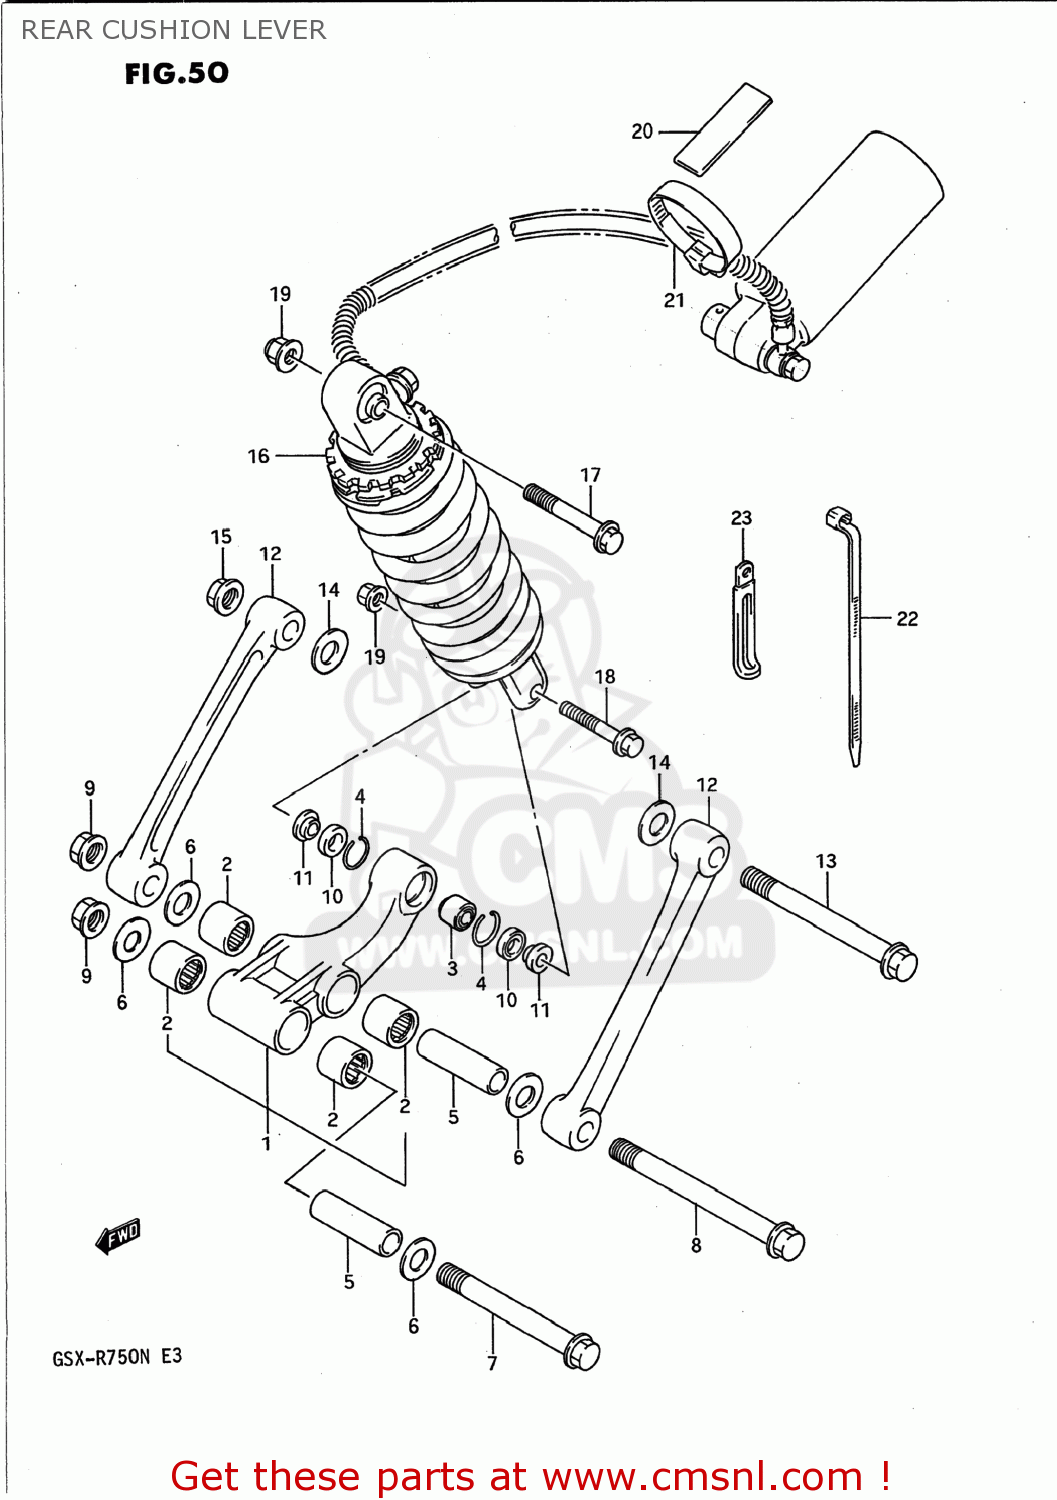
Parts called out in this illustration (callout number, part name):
1	LEVER SET,REAR CUSHION
2	BEARING(20X27X23.5)
3	BEARING,RR CUSHION LEVER
4	RING,STOPPER
5	SPACER,RR CUSHION LEVER
6	WASHER
7	SHAFT,RR CUSHION LEVER FR
8	SHAFT,RR CUSHION ROD
9	NUT
10	DUST SEAL,RR CUSHION LEVER RR
11	SPACER
12	ROD,REAR CUSHION
13	SHAFT,RR CUSHION ROD
14	WASHER
15	NUT
16	ABSORBER ASSEMBLY,REAR SHOCK
17	BOLT
18	BOLT(10X54)
19	NUT
20	CUSHION,RESERVOIR TANK
21	CLAMP
22	CLAMP(L:165)
23	CLAMP
